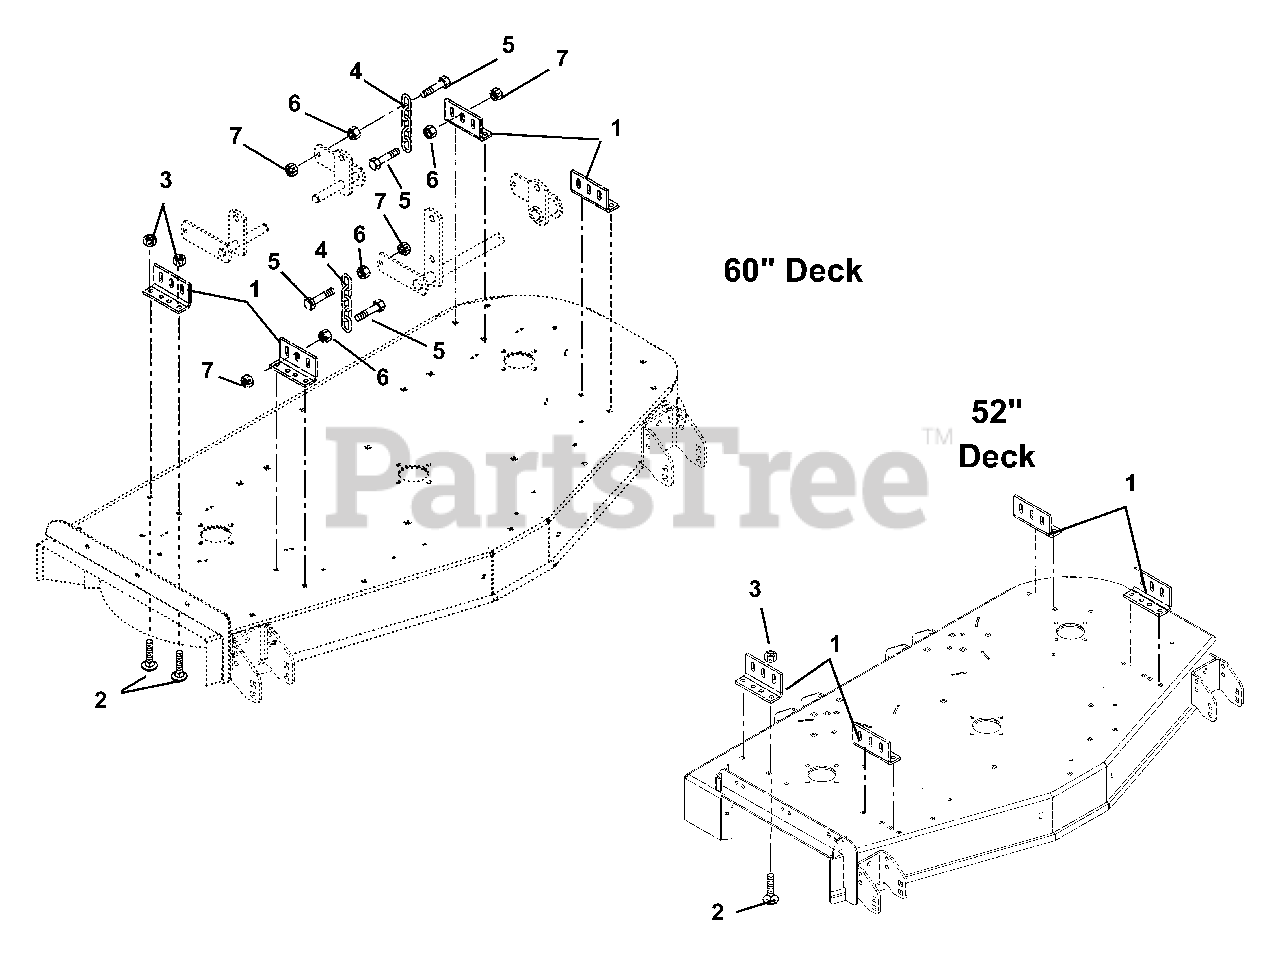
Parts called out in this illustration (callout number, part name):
1	MOWER MOUNTING BRACKET - RED
2	@BLT-RDHDSQNK .38-16X1.00 G5YZ
3	@NUT-LK-TOP-FLG .38-16 YWZC
4	CHAIN, LINK
5	BLT-HEX M12X1.75X55 GR5 YZ
6	NUT-SPNLK-FLG M12-1.75 YZ
7	NUT-LK-TOP-FLG M12-1.75 YZ
